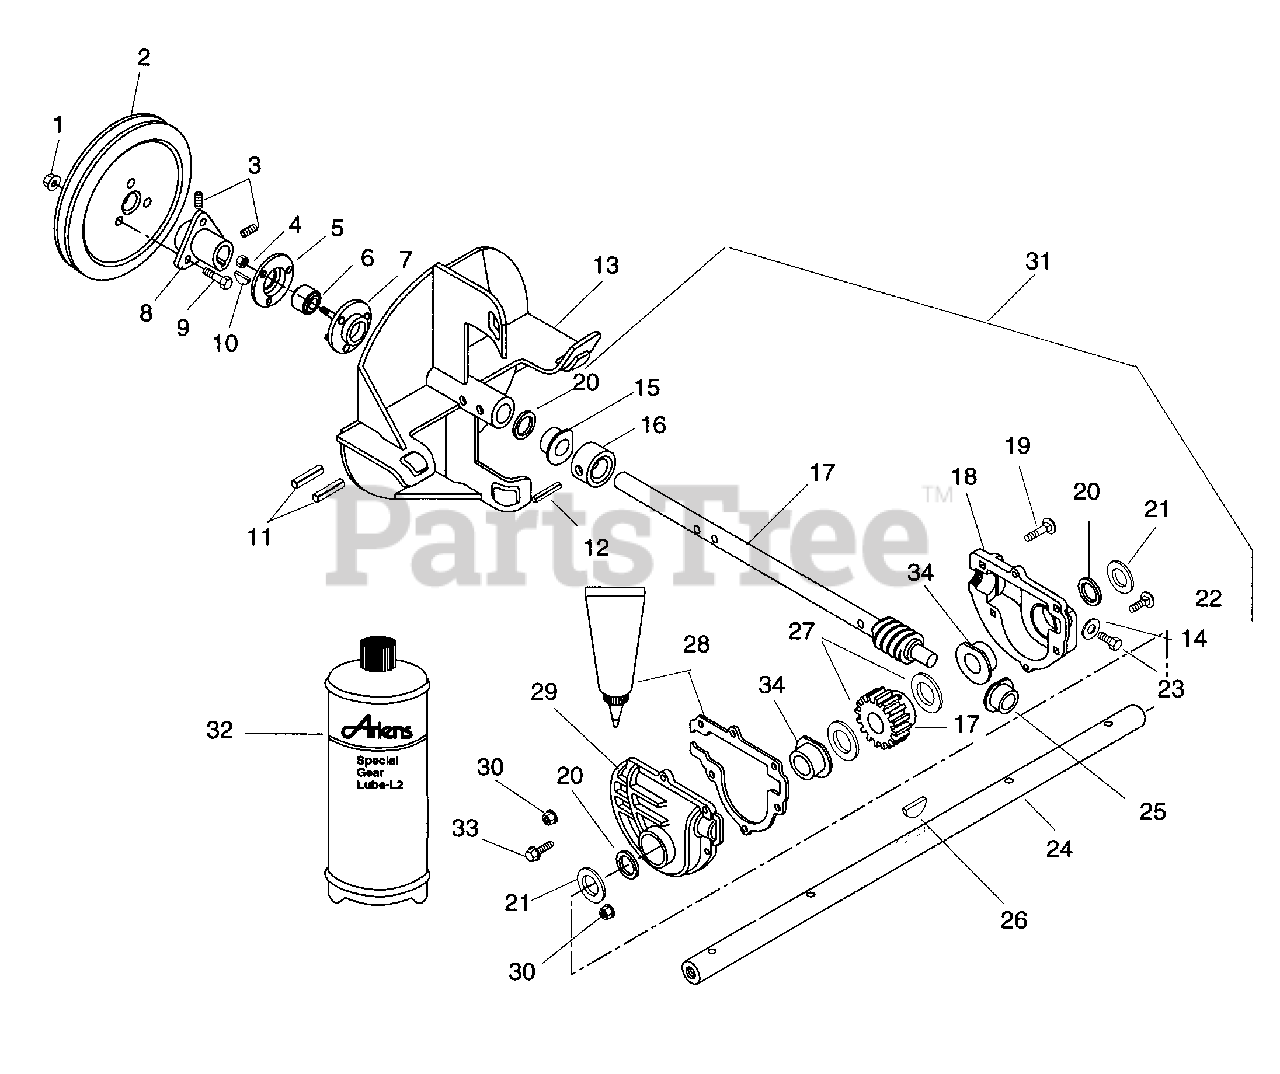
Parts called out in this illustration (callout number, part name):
1	NUT-FLG. .312-18 PL
2	PLY-V 8.50 X 1.25 3BLT
2	PLY-V 7.0 X 1.25 3 BLT
3	SCR-SET .31-18X.38 SKHCUPDL
4	NUT-LK-CTR .250-20 PL
5	BEARING FLANGE
6	BRG-BALL .750X1.750X.50
7	BEARING FLANGE
8	HUB
9	BLT-SERRDHD SL .31-18X.75 YZ
10	KEY-WDRF .188X.875X.375 SAE11
11	PIN-ROLL .250X1.25
12	PIN-GRV .188X1.25 TP A
13	IMPELLER - 10"
14	WSHR-FIBER .437X.656X.032
15	BSHG-FLG .750X1.000X.750X1.250
16	THRUST COLLAR
17	SHAFT AND WORM GEAR ASSEMBLY
18	LS CASE HALF LH SMALL BORE
19	BLT-RDHDSQNK .25-20X1.25 GR5PL
20	SEAL-OIL .750X1.375X.250
21	WSHR-FL-STL.812X1.500X.139
22	BLT-RDHDSQNK .25-20X.88 PL
23	SCR-TAP .375-16X .50 HWH PL TR
24	SHAFT, RAKE - 20"
24	SHAFT, RAKE - 24"
25	BSHG-FLG .500X.750X.750X1.000
26	KEY-WDRF .188X.625X.25 SAE 61
27	WSHR-HDND-THRST .755X1.40X.062
28	LOCTITE 518 GASKET--6ML TUBE
29	LS CASE HALF RH SMALL BORE
30	NUT-LK-FLG .250-20 PL
31	GEAR CASE - 20" - ALUMINUM
31	GEAR CASE - 24" JD - ALUMINUM
32	BOTTLE ONLY-S.SCREEN.FOR NO.80
33	SCR-TAP 10-24X.75 HWH PL TR
34	BSHG-FLG .75X1.00
